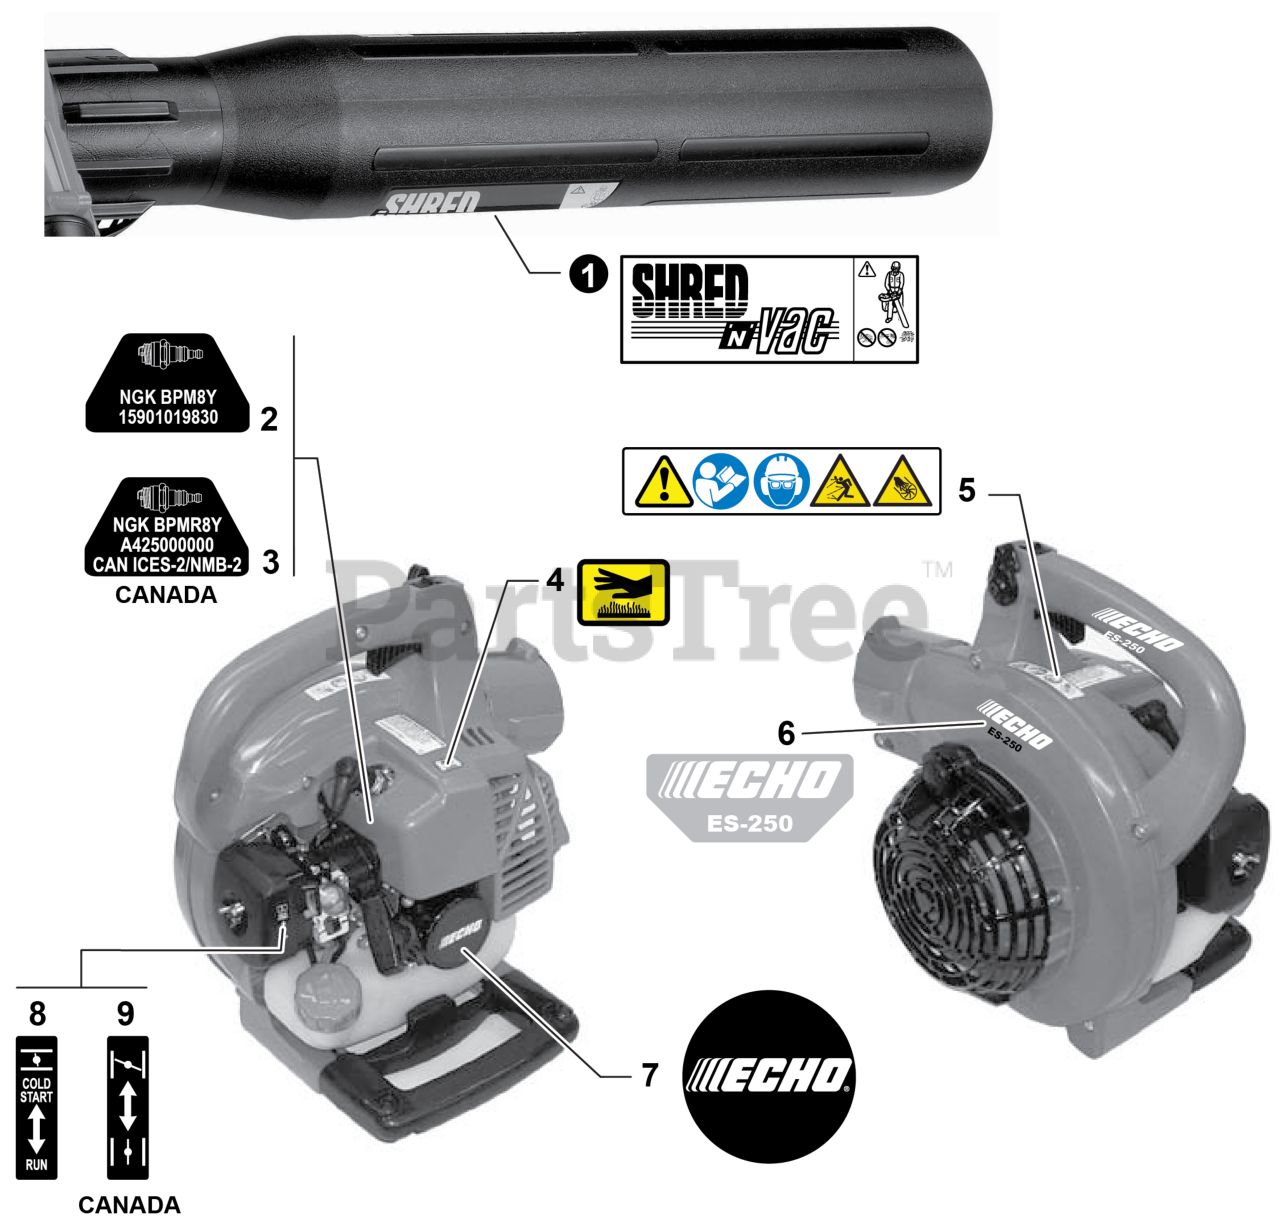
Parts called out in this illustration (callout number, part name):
1	LABEL - SHRED 'N' VAC
2	LABEL - SPARK PLUG - BPM8Y
3	LABEL - SPARK PLUG - BPMR8Y
4	LABEL - CAUTION - HOT
5	LABEL - CAUTION - ISO
6	LABEL - MODEL ES-250
7	LABEL - STARTER - ECHO
8	LABEL - CHOKE
9	LABEL - CHOKE
